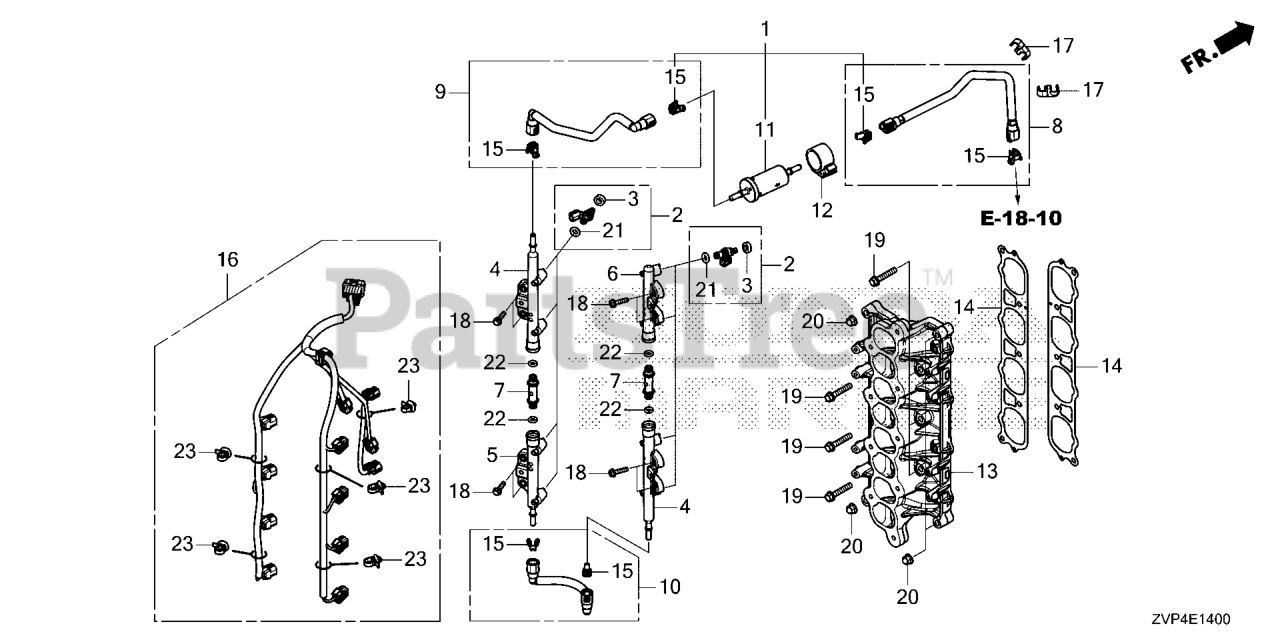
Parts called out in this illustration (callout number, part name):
1	FILTER ASSY., FUEL (HIGH)
2	INJECTOR ASSY., FUEL
3	RING, SEAL
4	PIPE COMP A, FUEL
5	PIPE COMP B, FUEL
6	PIPE COMP C, FUEL
7	JOINT, FUEL PIPE
8	HOSE COMP A, FUEL
9	HOSE COMP B, FUEL
10	HOSE COMP C, FUEL
11	STRAINER, FUEL (HIGH)
12	SUSPENSION, STRAINER
13	BASE, INJECTOR
14	GSKT, INJ BASE
16	HARN ASSY.
17	CLIP, SENSOR HOSE
18	BOLT, FLANGE (6X25)
19	BOLT, FLANGE (8X45)
21	O-RING (6.3X2.2)
22	O-RING (7.47X3.6)
23	CLIP, HARNESS BAND (151.5MM) (NATURAL)
